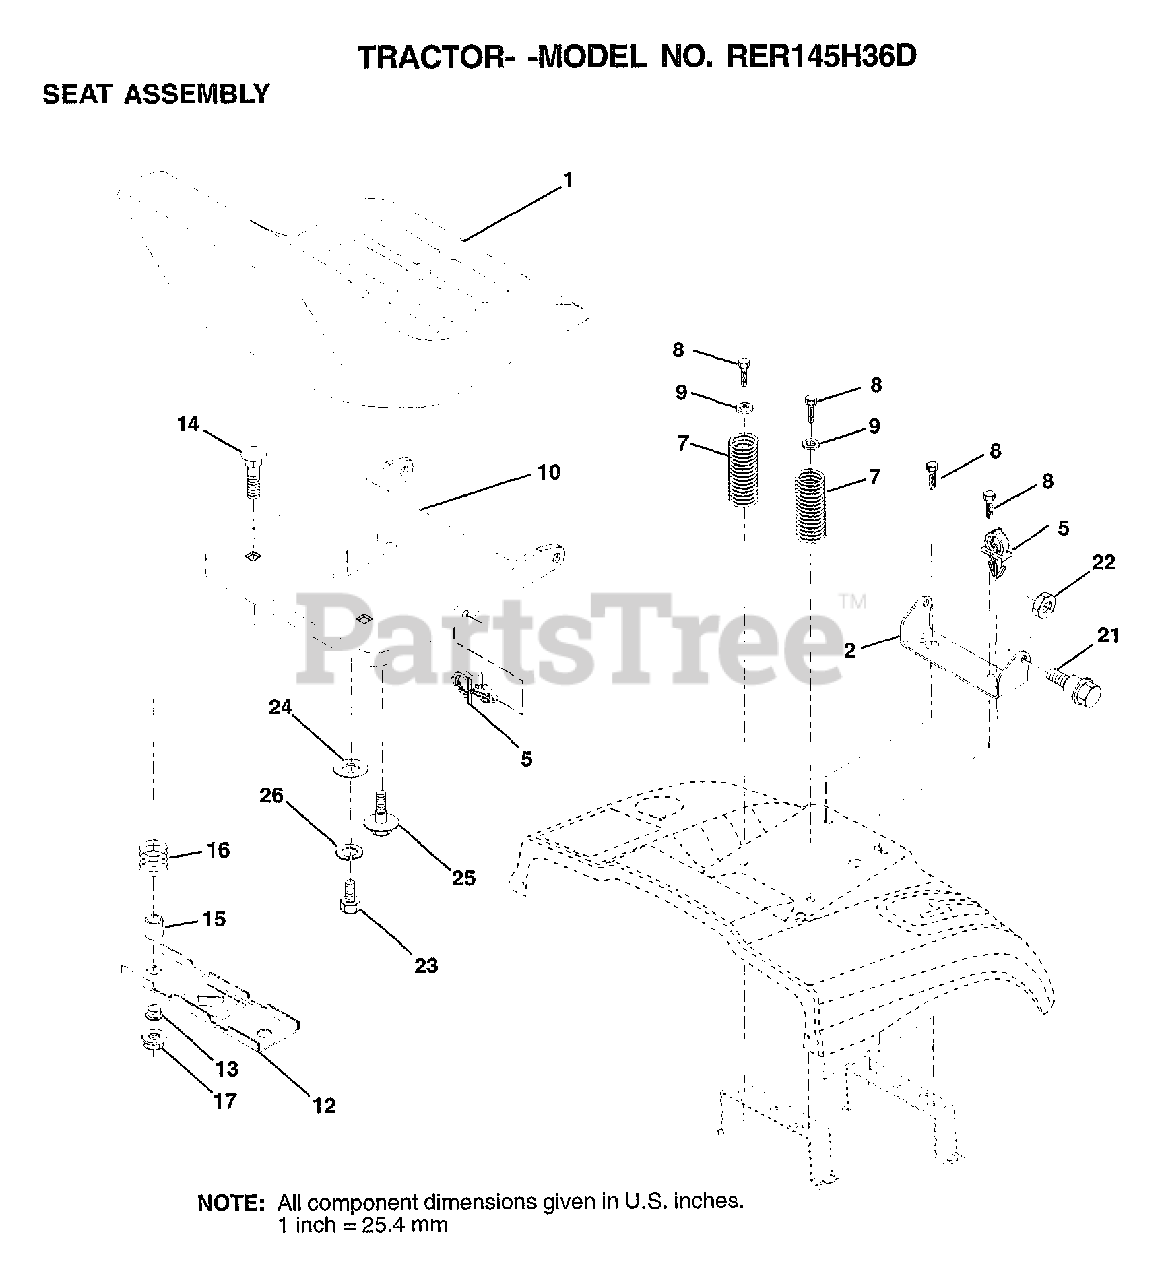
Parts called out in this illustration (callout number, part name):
2	BRACKET PVT SEAT
5	CLIP.PUSH-IN.HING
7	SPRING COMPRESSIO
8	SCREW
9	WASHER
10	PAN-SEAT
12	BRKT SWITCH
13	BUSHING
14	BOLT-RD HD SQ NK
15	SPLIT SPACER
16	SPRING
21	BOLT
22	NUT
23	BOLT HEX BLACK
24	WASHER
25	"BOLT,SHOULDER"
26	LOCKWASHER
